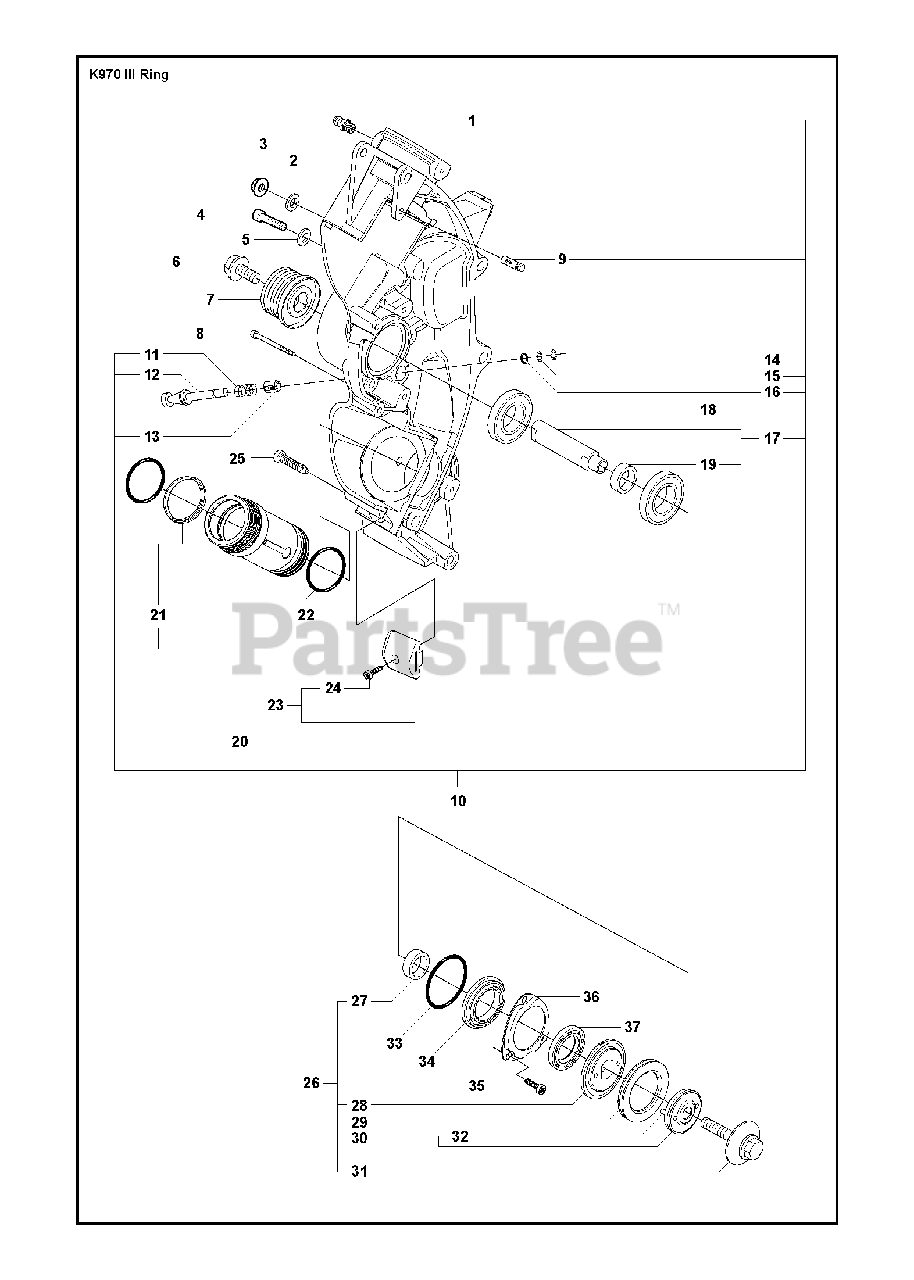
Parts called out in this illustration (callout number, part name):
1	LUBRICATION NIPPLE
8	SCREW ITXSCM
10	CHASSISIncl. 1, 9, 11 - 17, 20
17	DRIVE SHAFTIncl. 18 - 19
18	BALL BEARING
20	SLEEVEIncl. 21 - 22
23	WEAR PROTECTIONIncl. 24
25	SCREW ITXSCM
26	GEAR WHEEL ASSYIncl. 27 - 32
35	SCREW ITXSCM
37	SEALING RING
